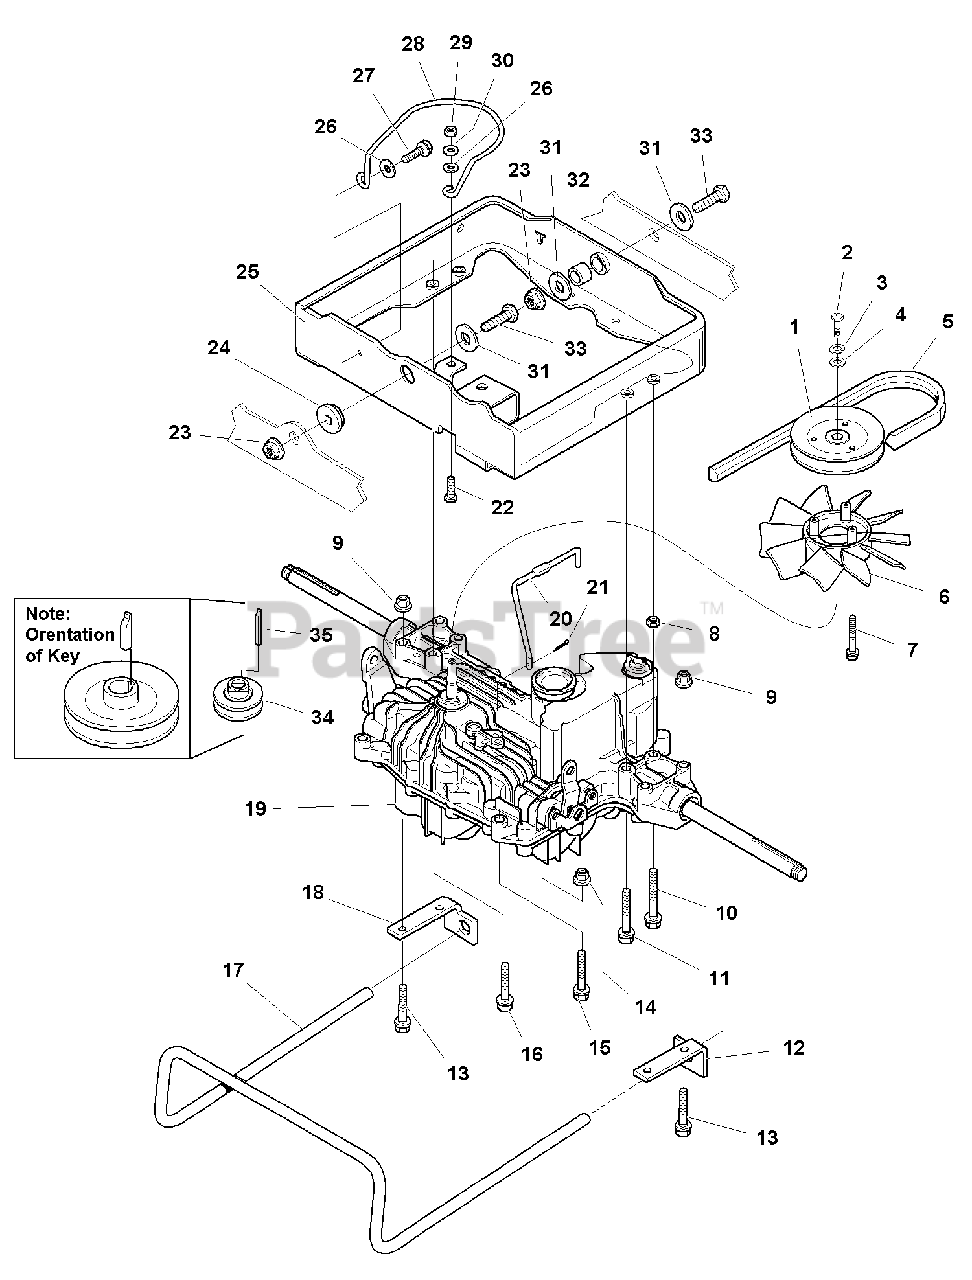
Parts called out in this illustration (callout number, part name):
1	PULLEY ASSEMBLY
2	CAPSCREW, Hex Head, M06-1 x 20mm
3	LOCKWASHER, 1/4
4	WASHER, 1/4
5	BELT, Drive
6	FAN, 10 Blade
7	CAPSCREW, Taptite Hex Washer Head, 1/4-20 x 1-1/2
8	JAM NUT, Top Lock, 5/16-18
9	NUT, Hex Flange Whiz-Lock, 5/16-18
10	CAPSCREW, Taptite Hex Washer Head, 5/16-18 x 3-1/2
11	CAPSCREW, Taptite Hex Washer Head, 5/16-18 x 3
12	ANCHOR, Torsion Bar, LH
13	CAPSCREW, Hex Head Whiz Lock, 5/16-18 x 2-1/2
14	NUT, Hex Flange Whiz Lock, 5/16-18
15	CAPSCREW, Hex Head Whiz Lock, 5/16-18 x 1-1/4
16	CAPSCREW, Taptite Hex Washer Head, 5/16-18 x 2-1/2
17	TORSION BAR
18	ANCHOR, Torsion Bar, RH
19	TRANSMISSION ASSEMBLY & PULLEY KIT, Tuff Torq K-56 (Includes Ref. Nos. 1, 2, 3, & 4)
20	ROD, Transmission Release
21	COTTER PIN
22	CAPSCREW, Hex Head, 5/16-18 x 1
23	NUT, Hex Flange Lock, 1/2-13,
25	CARRIER, Transmission, Hydro
26	WASHER, 5/16
27	CAPSCREW, Taptite Hex Washer Head, 5/16-18 x 3/4
28	GUIDE, Belt
29	NUT, Hex, Full, 5/16-18
30	LOCKWASHER, 5/16
31	WASHER, 1/2
33	CAPSCREW, Hex Head, 1/2-13 x 1-1/2
34	PULLEY & HUB ASSEMBLY
